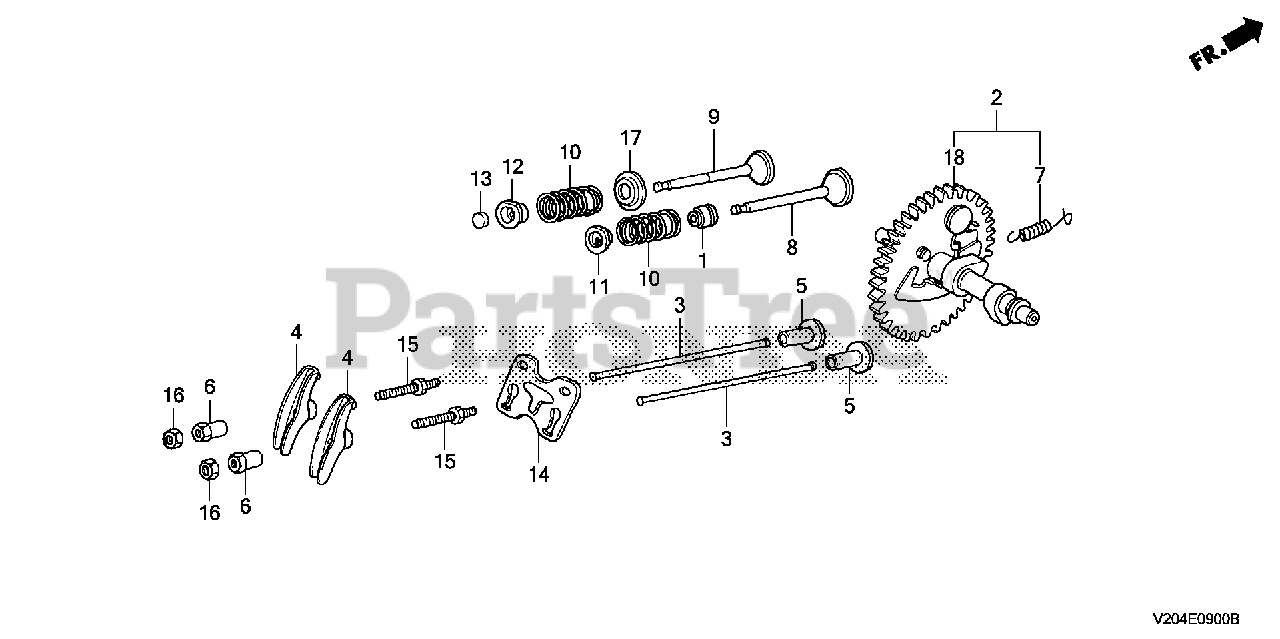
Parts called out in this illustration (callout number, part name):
1	SEAL, VALVE STEM
4	ARM, VALVE ROCKER
5	LIFTER, VALVE
6	PIVOT, ROCKER ARM
8	VALVE, IN.
9	VALVE, EX.
10	SPRING, VALVE
11	RETAINER, IN. VALVE SPRING
12	RETAINER, IN. VALVE SPRING (EXHAUST SIDE)
14	GUIDE, PUSH ROD
15	BOLT, PIVOT (8MM)
16	NUT, PIVOT ADJUSTING
17	SEAT, VALVE SPRING
18	CAMSHAFT (STD) (PRESS FIT CAM)
